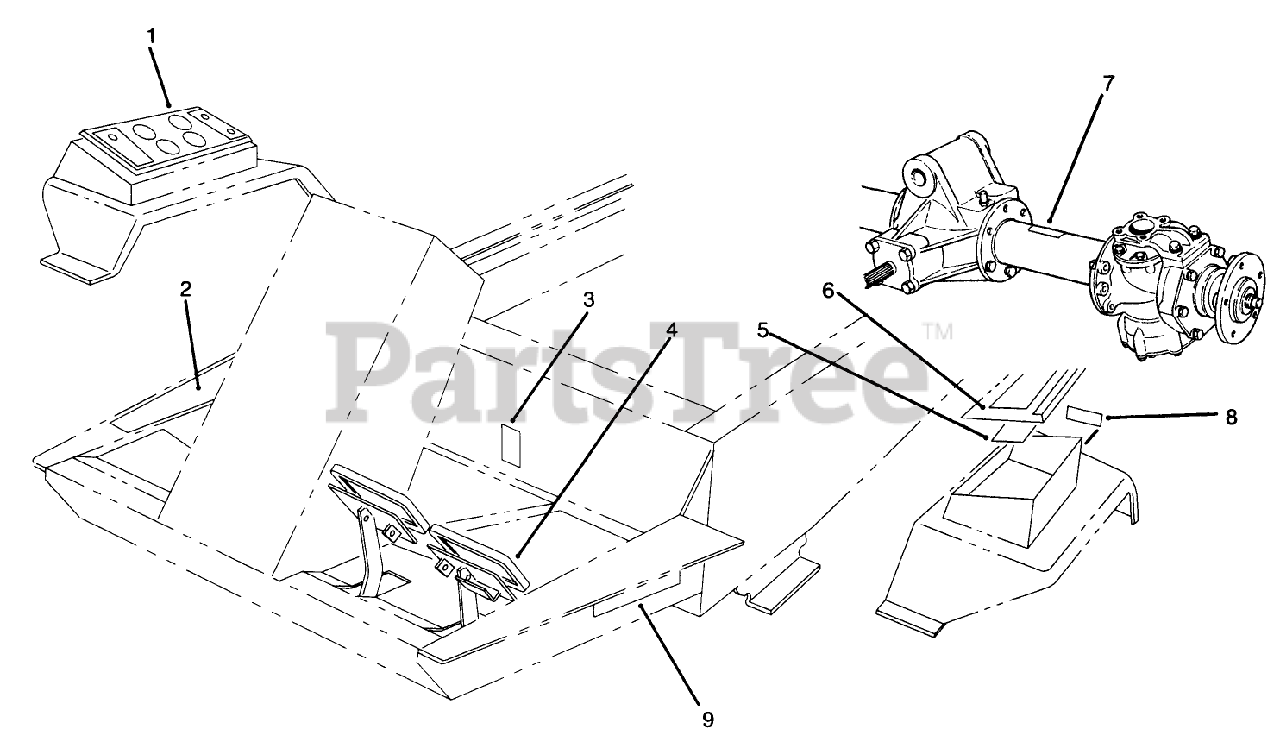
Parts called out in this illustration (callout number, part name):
1	PANEL-CONTROL
2	DECAL-FOOTREST, RH
3	DECAL-OIL
4	FOOTPAD-BRAKE
5	DECAL-BLANK
6	DECAL - WARNING
6	DECAL-DANGER
7	DECAL-LUBE
8	DECAL-REFUELING
9	DECAL-TORQUE
